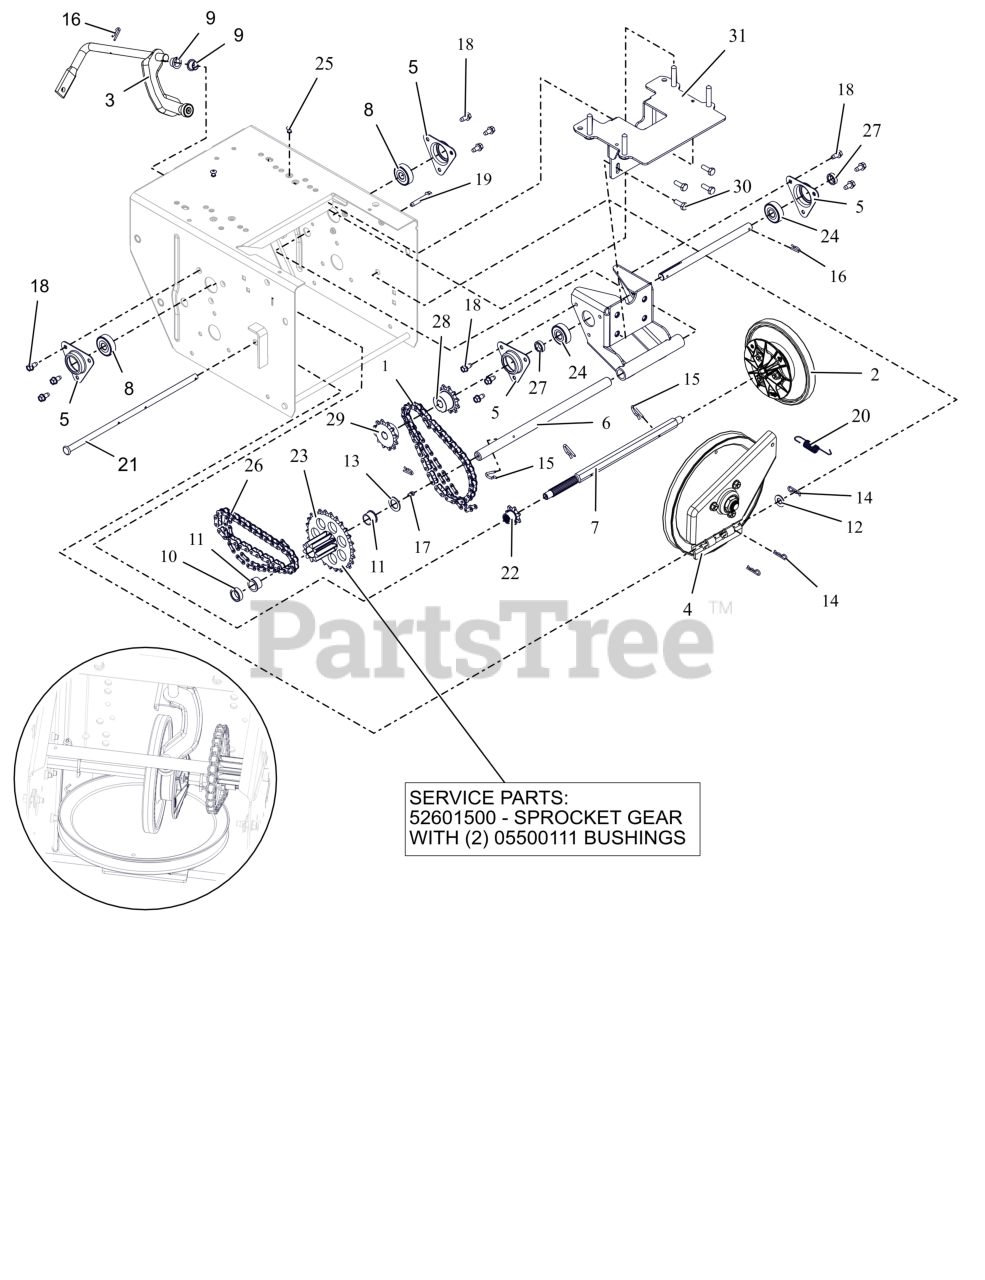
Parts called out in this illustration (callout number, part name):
1	CHAIN, ROLLER - #41X36 PITCHES
2	DISC, FRICTION DRIVE-ASSEMBLY
3	ARM, SHIFT - ASSEMBLY
4	PLATE, SWING ASSEMBLY-DEEP
5	FLANGE, BEARING
6	SHAFT, PINION-HARDENED
7	SHAFT, HEX HEAT TREATED SPLINE
8	BRG-BALL .437X1.375X.437
9	BUSHING, POLYLINER-.50 SPLIT
10	BSHG-SLV, .635X.880X.305
11	BSHG-FLG .625X.750X.500X.875
12	WSHR,FLT .406X.812X.065 ZCC
13	WSHR, FLT .630X1.005X.062 ZCC
14	PIN, HAIR #213 .08X1.19 ZCC
15	PIN, SPRING CLIP
16	CLIP, SPRING
17	ZERK,FITTING .25X.125 DRIVE IN
18	SCR-TAP .25-20X.50 HWH ZCC
19	SCR,TAP .25-20X1.50 HWH TR ZCC
20	SG-TENS .048X.50X2.8
21	PIN, PIVOT
22	SPROCKET, PINION 7T W/SPLINE
23	PINION & SPROCKET
23	PINION & SPROCKET W/BUSHINGS
24	BRG-BALL .500X1.38X.437
25	RVT, POP .1875 ZCC
26	CHAIN - #41, 32 PITCHES
27	SPCR, SLV
28	SPROCKET, 11 TOOTH
29	SPROCKET, 12 TOOTH
30	BLT, HEX .25-20X.75 G5 ZCC
31	STRAP, TRIPLE REDUCTION MEDIUM
